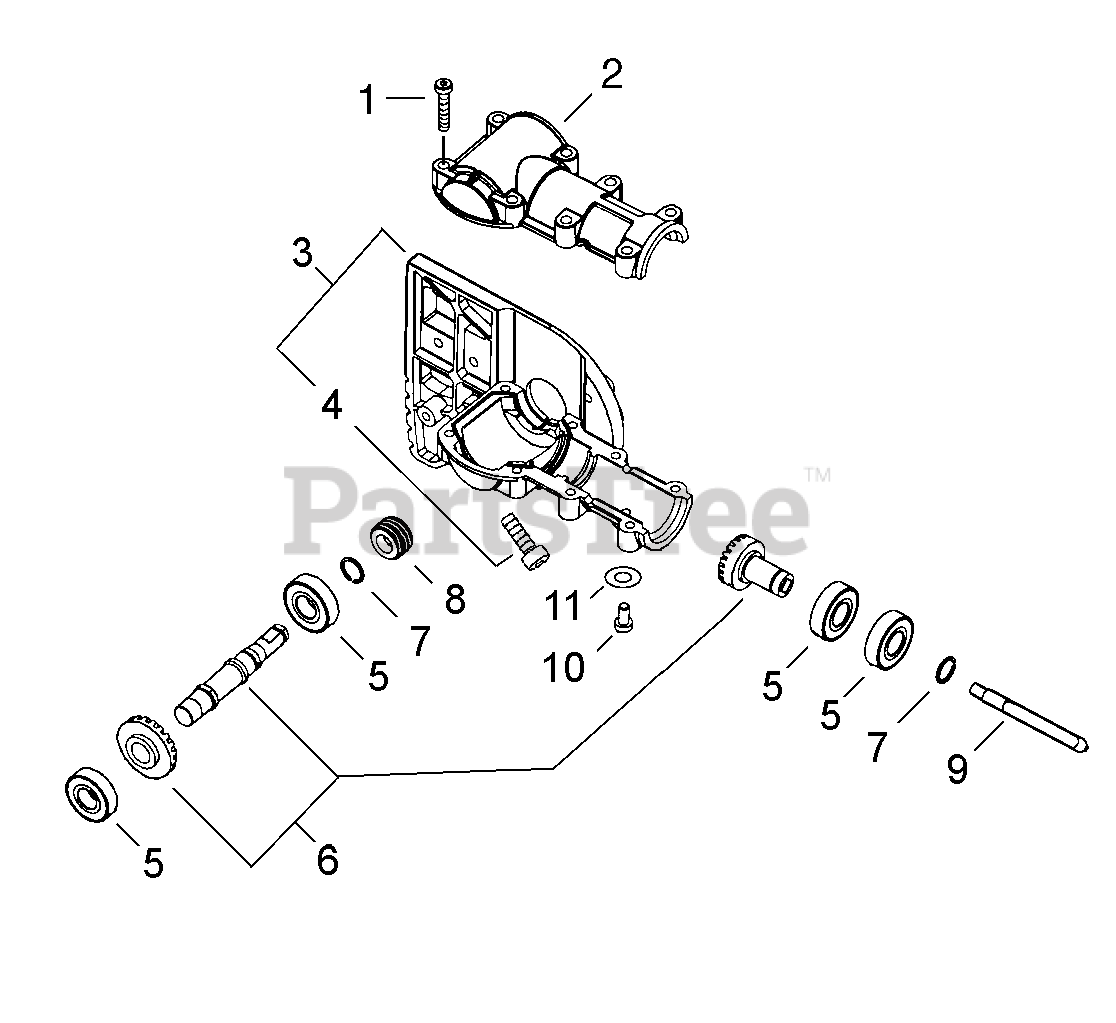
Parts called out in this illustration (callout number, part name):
1	BOLT 5×0.8×25
2	CASE, GEAR - UPPER Ø35
3	CASE ASSY, LOWER GEAR
4	BOLT 5×10
5	BEARING, BALL
6	SHAFT KIT, GEAR
7	RING, SNAP Ø12
8	GEAR, WORM
9	CONNECTOR, DRIVE SHAFT
10	BOLT 5×10
11	WASHER, FLAT 5.5×10×0.8
